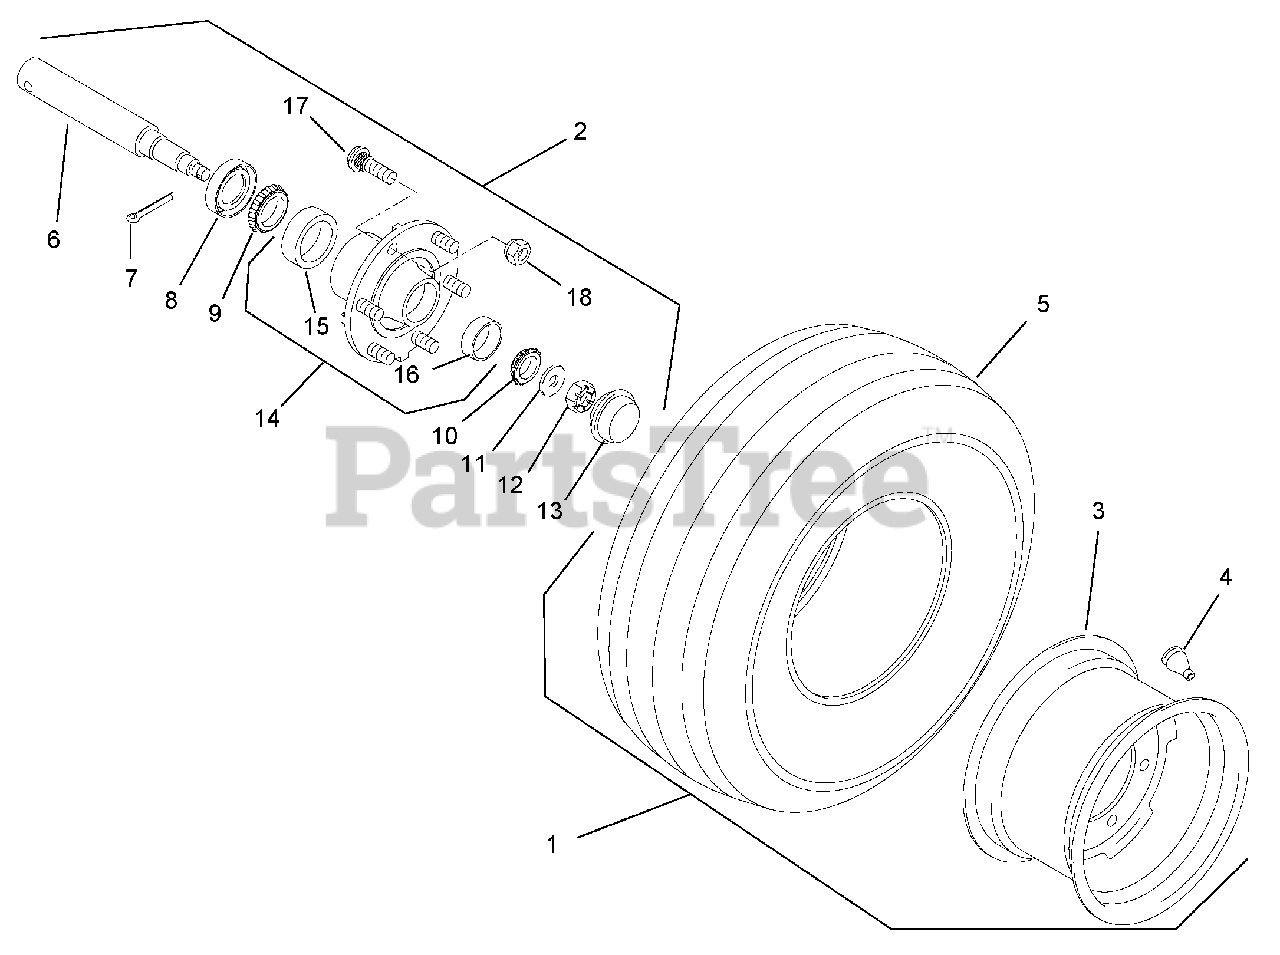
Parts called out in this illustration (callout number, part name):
1	Tire and Wheel Assembly
2	Hub and Spindle Assembly (includes items 6 – 18)
3	Wheel 12 x 7
4	Valve Stem
5	Tire, 23 x 9.50-12
6	Spindle, 1.625
7	PIn, Cotter .156 x 1.50
9	Bearing 1.50
10	Cone, Bearing 1.25 I.D. x .66
11	Washer, Flat .875
12	Nut, Castellated Hex .875-14
14	Hub With Cups and Bolts
15	Bearing 1.50
16	Cup, Bearing
17	Bolt, Lug .50 x 1.875
18	Nut, Hex Hub .50-20 UNF
